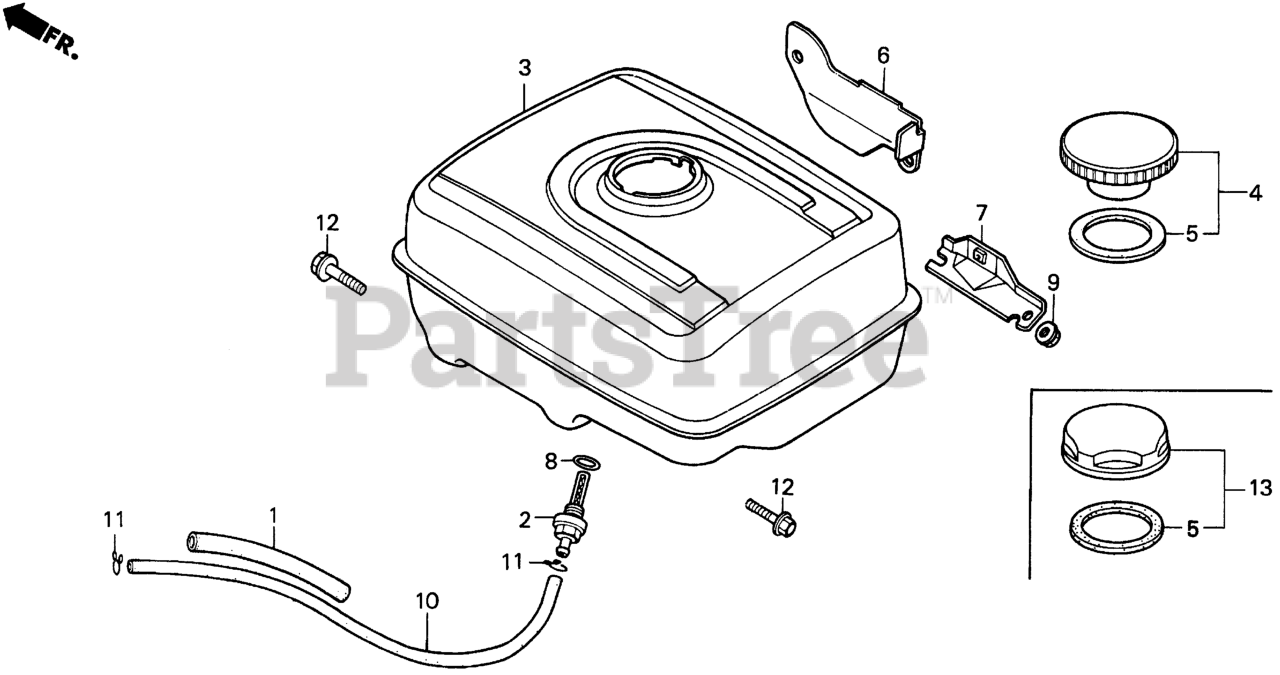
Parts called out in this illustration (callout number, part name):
1	RUBBER, SUPPORTER (107MM)
2	JOINT, FUEL TANK
3	TANK, FUEL *NH31* (MCKINLEY WHITE)
4	CAP, FUEL FILLER (BLACK) Use up to Engine SN 2115700.
4	CAP, FUEL FILLER (CHROME PLATED)
4	CAP COMP
5	GASKET, FUEL FILLER CAP (39X58X3) (NOT AVAILABLE)
5	GASKET, FUEL FILLER CAP Use from Engine SN 1543258.
5	GASKET, FUEL FILLER CAP (39X58X3)
6	COVER, SNOW PLATE
7	HOLDER, HANDLE BRACKET
8	O-RING (14MM) (ARAI) Use up to Engine SN 2949254.
9	NUT, FLANGE (8MM)
10	BULK HOSE, FUEL (4.5X3000) (Honda Code 5137104). (4.5X140)
11	CLIP, TUBE (B8)
12	BOLT, FLANGE (8X25)
13	CAP, FUEL FILLER
